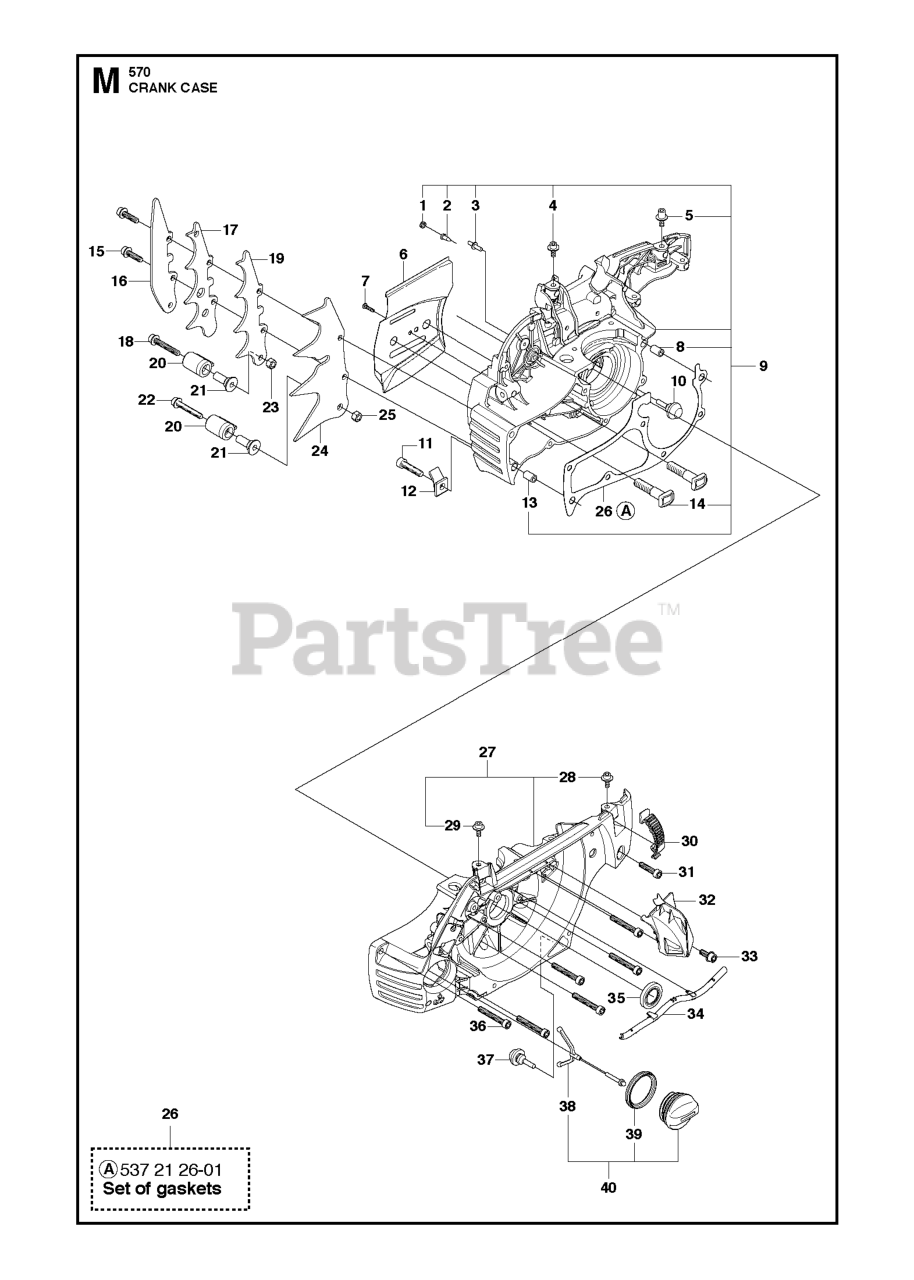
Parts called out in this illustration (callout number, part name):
1	PLUG
2	VALVE-CHECK (DUCKBILL)
4	SCREW IHSCM
5	SCREW IHSCM
9	RP CRANKCASE ASSEMBLY
12	CHAIN CATCHER
17	FELLING DOG
18	SCREW IHSCFM
19	FELLING DOG
21	CHAIN CATCHER
22	SCREW IHSCFM
24	FELLING DOG
26	GASKET SET
27	RP CRANKCASE ASSEMBLY
28	SCREW IHSCM
29	SCREW IHSCM
30	BUCKLE ORANGE
35	RADIAL SEAL
40	TANK CAP
